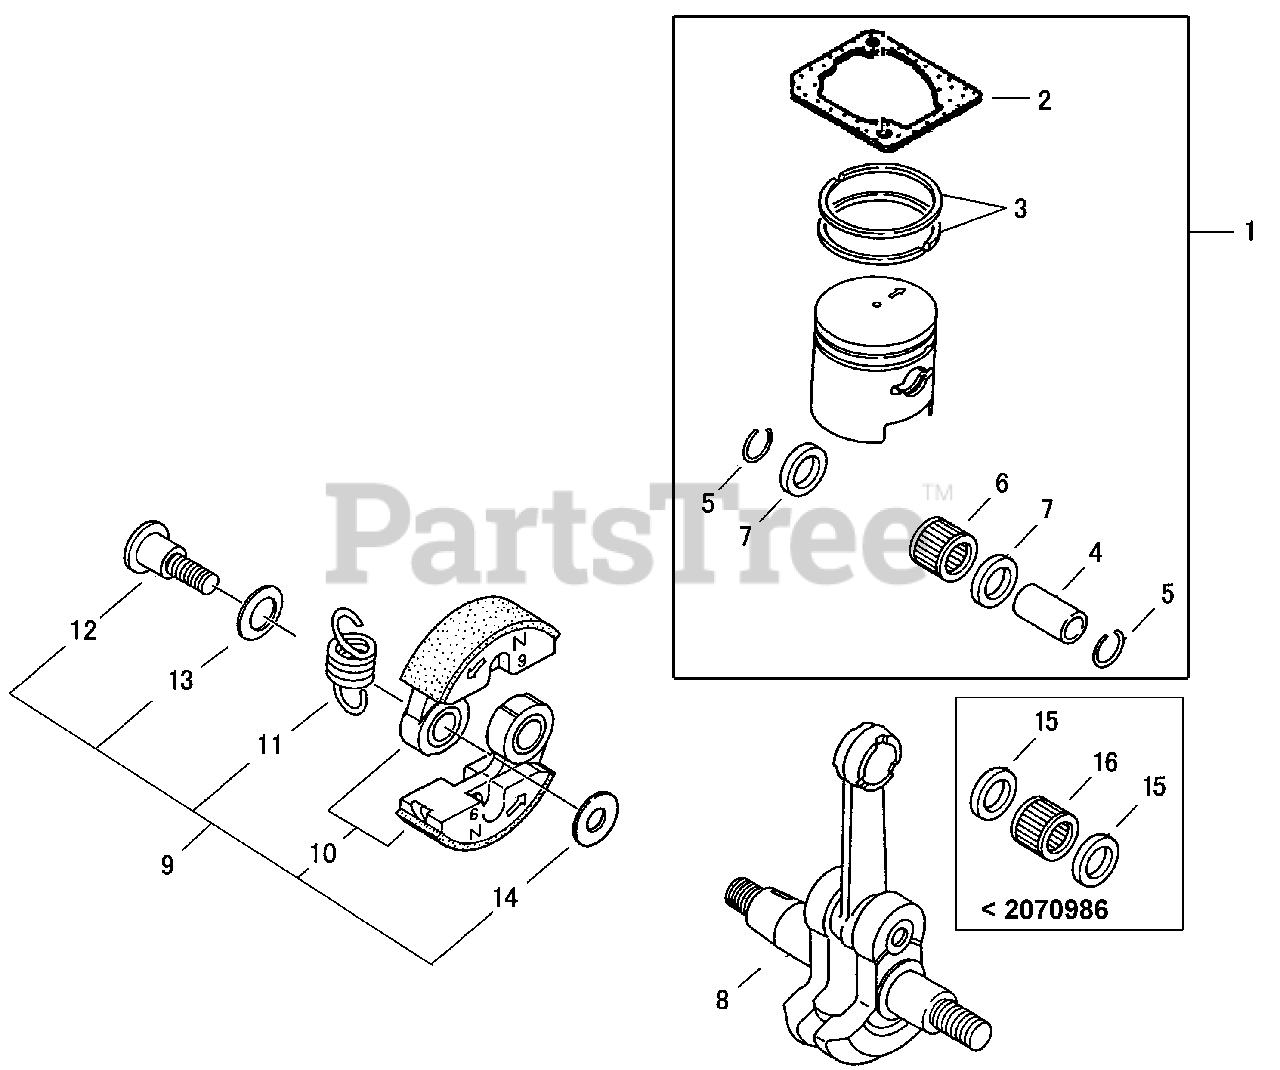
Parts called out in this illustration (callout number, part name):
1	PISTON KIT
2	GASKET, CYLINDER
3	RING, PISTON
4	PIN, PISTON 8
5	RING, SNAP
6	BEARING, NEEDLE 8
7	WASHER, THRUST 8
8	CRANKSHAFT
9	CLUTCH SHOE ASSY
10	SHOE, CLUTCH
11	SPRING, CLUTCH
12	BOLT
13	WASHER, SPRING
14	WASHER 6 MM
15	WASHER, THRUST
16	BEARING, NEEDLE
